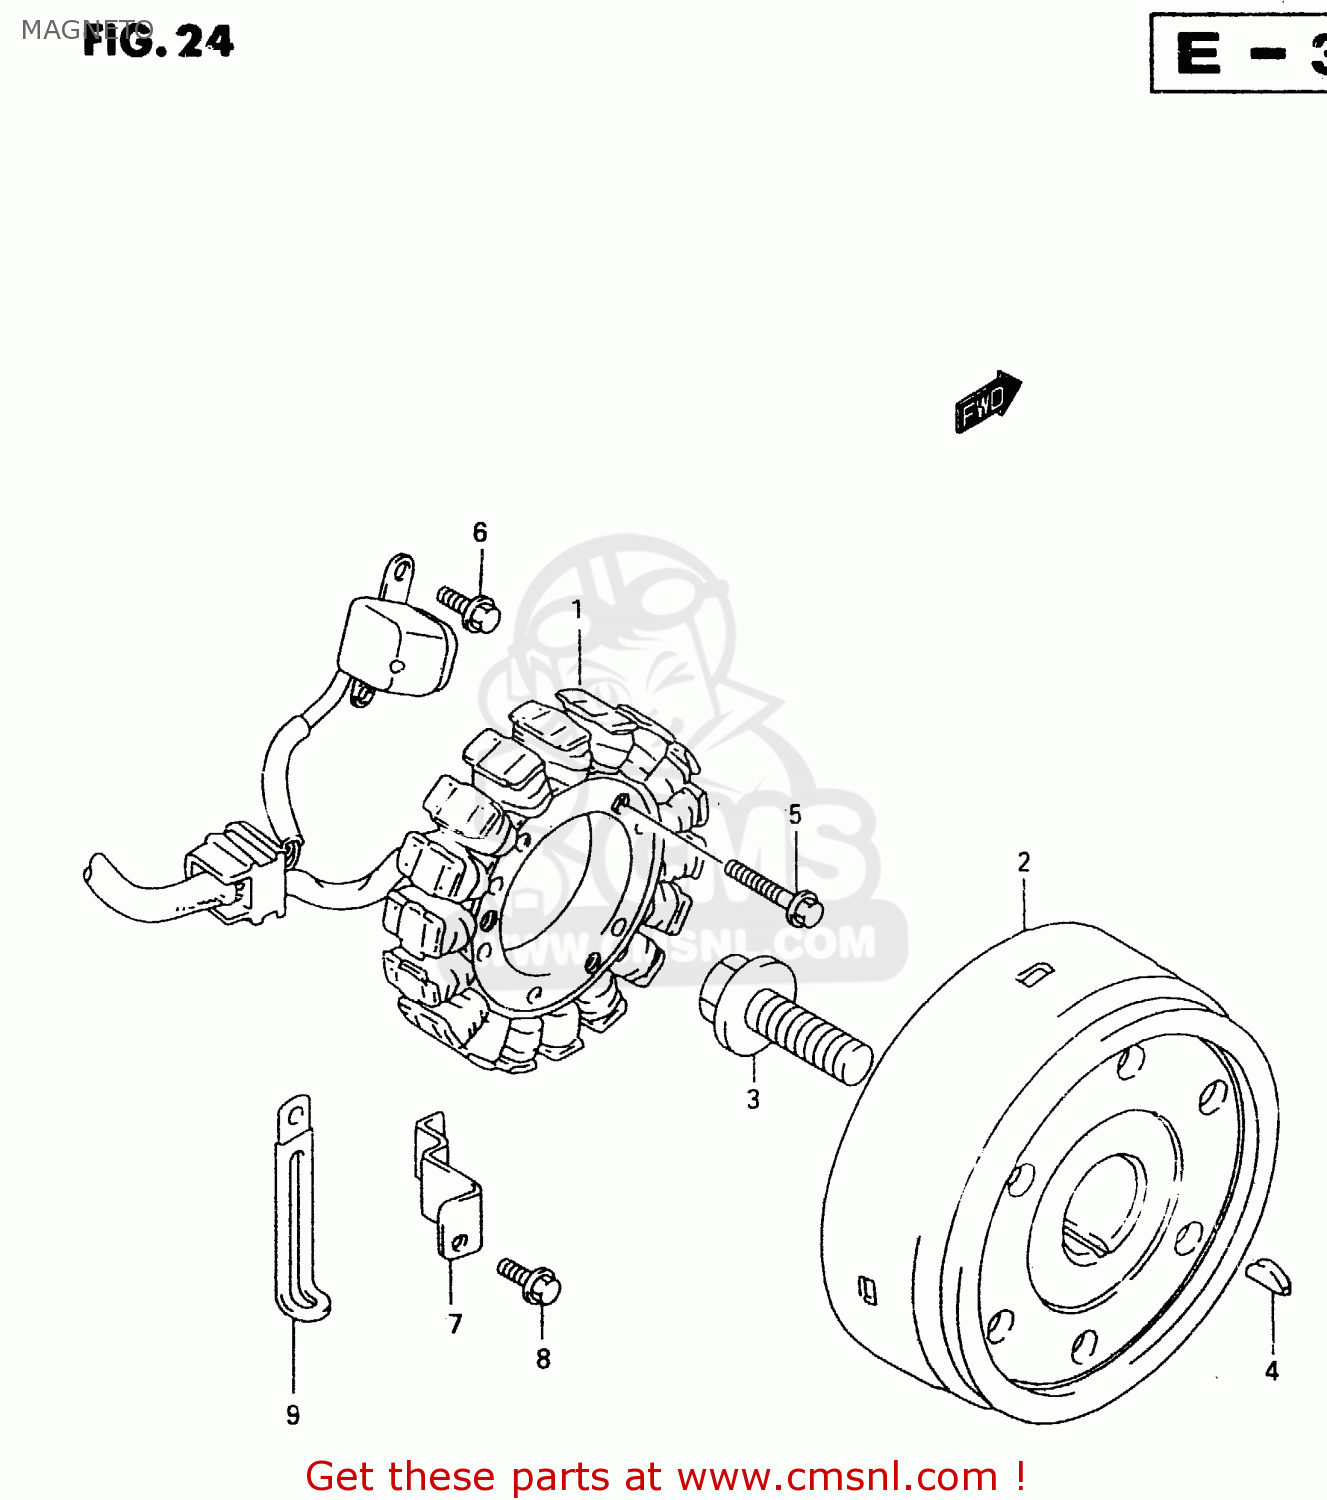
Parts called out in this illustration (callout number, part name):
1	STATOR ASSEMBLY,MAGNETO
2	ROTOR ASSY
3	BOLT(14X43)
4	KEY
5	BOLT,G/S SWITC
6	BOLT
7	CLAMP,MAGNETO LEAD WIRE
8	BOLT
9	CLAMP(L:45)
